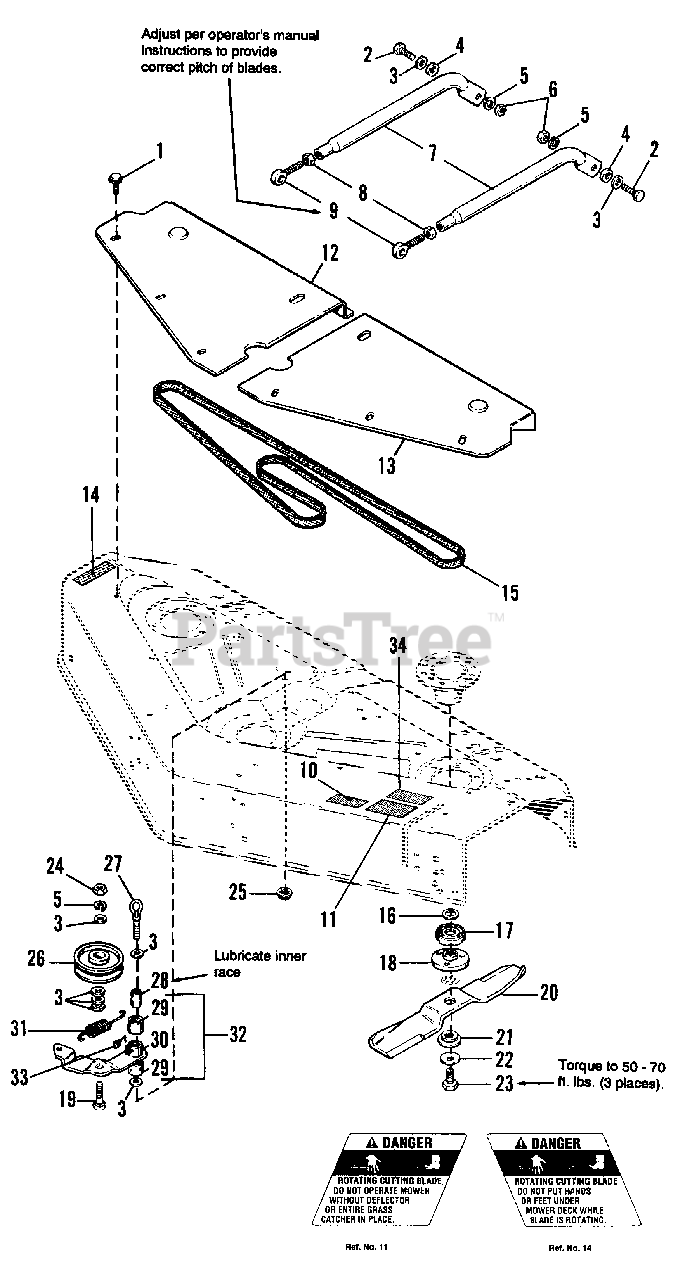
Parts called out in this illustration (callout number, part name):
1	SCREW. Hex, Taptite, 1/4-20 x 3/8
2	CAPSCREW, Hex Hd., 3/8-16 x 1
3	WASHER, Plain, 13/32
5	LOCKWASHER, 3/8
6	NUT, Hex, Full, 3/8-16
7	ARM, Adjusting
8	NUT, Hex, Jam, 1/2-20
10	DECAL, Belt Adjustment
11	DECAL, Danger, Deflector in Place
12	COVER, R.H. (Orange)
12	COVER, R.H. (Black)
13	COVER, L.H. (Orange)
13	COVER, L.H. (Black)
14	DECAL, Danger, Rotating Blade
15	V-BELT, Arbor Drive
16	WASHER, Shim
17	SHIELD, Grass
18	ADAPTER, Blade
19	CARRIAGE BOLT, 3/8-16 x 1-1/4
20	BLADE, 42" Mower
21	WASHER, Spline
22	WASHER, Spring
23	CAPSCREW, Hex Hd., 7/16-14 x 1
24	NUT, Hex, Jam, 3/8-16
25	NUT, Hex, Flange Whizlock, 3/8-16
26	PULLEY ASSY., Idler
32	LEVER ASSY., Idler (lncl. Ref. No. 29, 30 & 33)
33	FITTING, Grease, 1/4-28
34	DECAL, Cutting Width, 42"
